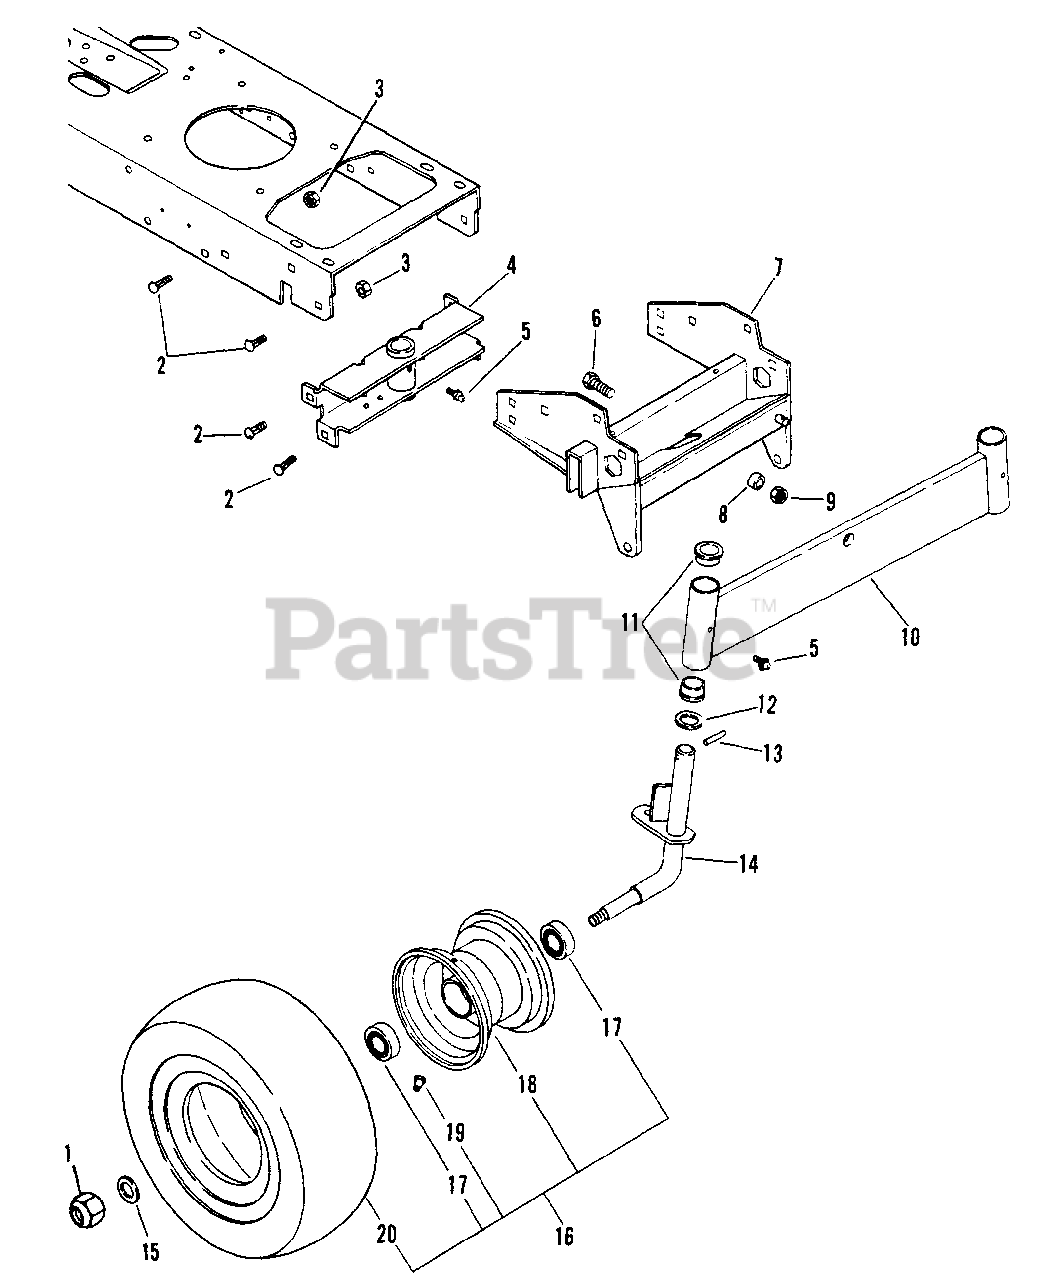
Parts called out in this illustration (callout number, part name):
1	Nut, Lock 5/8-11
2	Bolt, 3/8-16 x 1.00 Rd Hd Sq Nk
3	Nut, Lock 3/8-16
4	Channel, Pivot
5	Spin Drive Zerk Fitting
6	Bolt, Hex 1/2-13 x 1.50
7	Support, Front Axle
8	Spacer
9	Nut, Lock 1/2-13
10	Weldment, Front Axle
11	Bushing, Flange Steel
12	Bearing, Thrust Race
13	Pin, Spring .250 x 1.500
14	Weldment, Kingpin(R.H.)
14	Weldment, Kingpin(L.H.)
15	Washer, Flat .812 x 1.496 x .134
16	Assembly, Front Wheel
17	Bearing, Gauge Wheel
18	Assembly, Rim
19	Assemby, Valve Stem
20	Tire, Front 16 x 6.50-8
